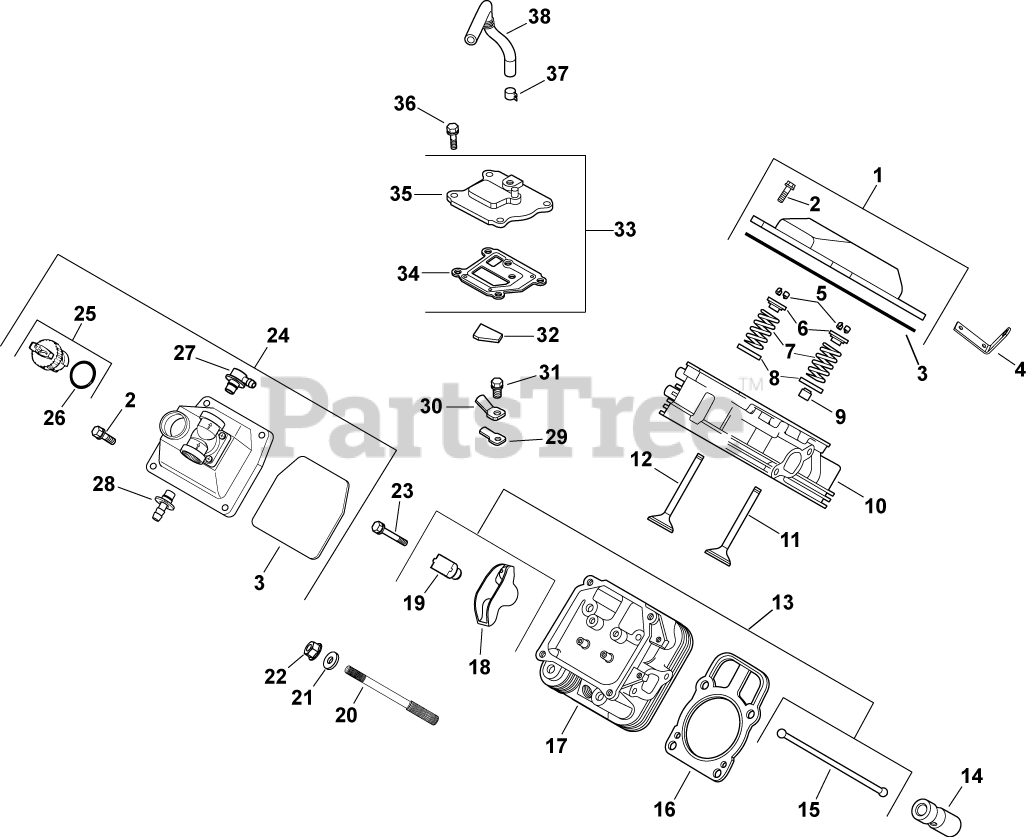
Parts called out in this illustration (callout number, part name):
1	KIT, VALVE COVER-PLAIN
2	SCREW, FLG M6X1.0X30
3	O-RING (YELLOW) -USE 24 153 30-S
4	STRAP, LIFTING-USE 25 445 03-S
5	KIT, RETAINER
6	RETAINER, VALVE SPRING - USE 25 173 28-S
7	SPRING, VALVE
8	RETAINER, SPRING
9	SEAL, VALVE STEM - (#2503214S)
10	HEAD, ASSEM CYLINDER #1 -USE 24 318 107-
11	VALVE, INTAKE (STD)
12	VALVE, EXHAUST (STD) - USE 32 016 01-S
13	KIT, VALVE TRAIN
14	LIFTER, HYDRAULIC VALVE-USE 25 351 10-S
15	ROD, PUSH
16	KIT, GSKT CYL HD (C22-23 674CC)
17	HEAD, ASSEM CYLINDER #2 -USE 24 318 115-
18	ARM, ROCKER
19	PIVOT, CYLINDRICAL ROCKER ARM-USE 24 599
20	STUD, M8X1.25
21	WASHER, FLAT 8.6 MM
22	NUT, FLG M8X1.25
23	SCREW, FLG M6X1.0X34
24	KIT, VALVE COVER-FUEL PUMP
25	CAP ASSY, OIL FILL (YELLOW)
26	O-RING-USE 24 153 32-S
27	KIT, STRAIGHT FITTING
28	KIT, 90 DEG. FITTING
29	REED, BREATHER
30	RETAINER, REED
31	SCREW, FLG THD FRM M5X.8X10
32	FILTER, BREATHER-USE 24 050 11-S
33	KIT, BREATHER ASSEMBLY
34	GASKET, BREATHER-USE 24 041 67-S
35	COVER, BREATHER -USE 24 033 01-S
36	SCREW,FLG THD FRM M6X1.0X20-(#25086396S)
37	CLAMP, HOSE (KM)-USE 25 237 31-S
38	HOSE, BREATHER-USE 24 326 89-S
2401602-S	VALVE, EXHAUST (.25)
2401702-S	VALVE, INTAKE (.25)
